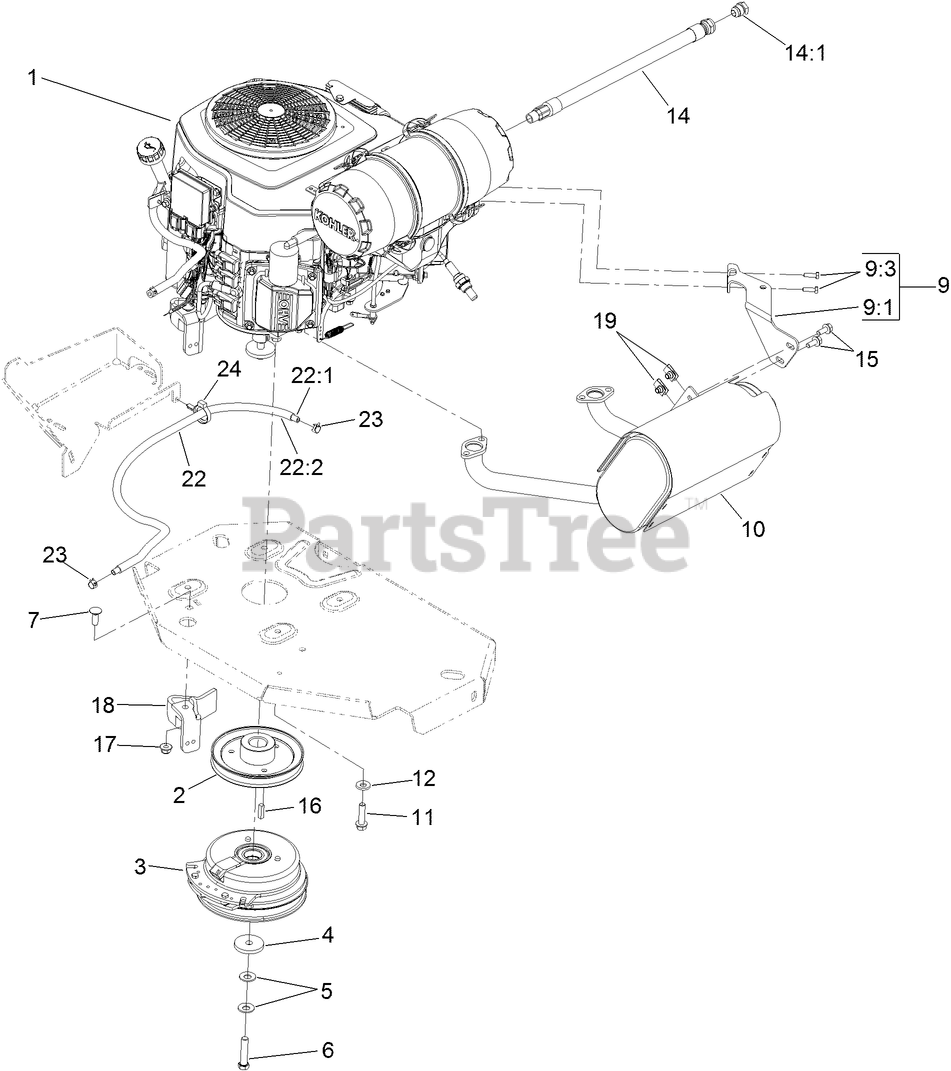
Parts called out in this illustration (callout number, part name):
2	SHEAVE
3	CLUTCH KIT
4	WASHER-CLUTCH
5	WASHER-SPRING
6	SCREW-HH W/LOCTITE
7	SCREW-CARR
9	MUFFLER BRACKET KIT
9:1	BRACKET-MUFFLER
9:3	SCREW-HH
10	MUFFLER
11	SCREW-HWH
12	WASHER-BELLEVILLE
14	OIL DRAIN HOSE ASM
15	SCREW-HHF
17	NUT-HF, NI
18	CLUTCH-ANCHOR
19	NUT-U
22	FUEL LINE ASM
22:1	HOSE-FUEL
22:2	SLEEVE-THERMAL
23	CLAMP-HOSE
24	CLAMP-HOSE
